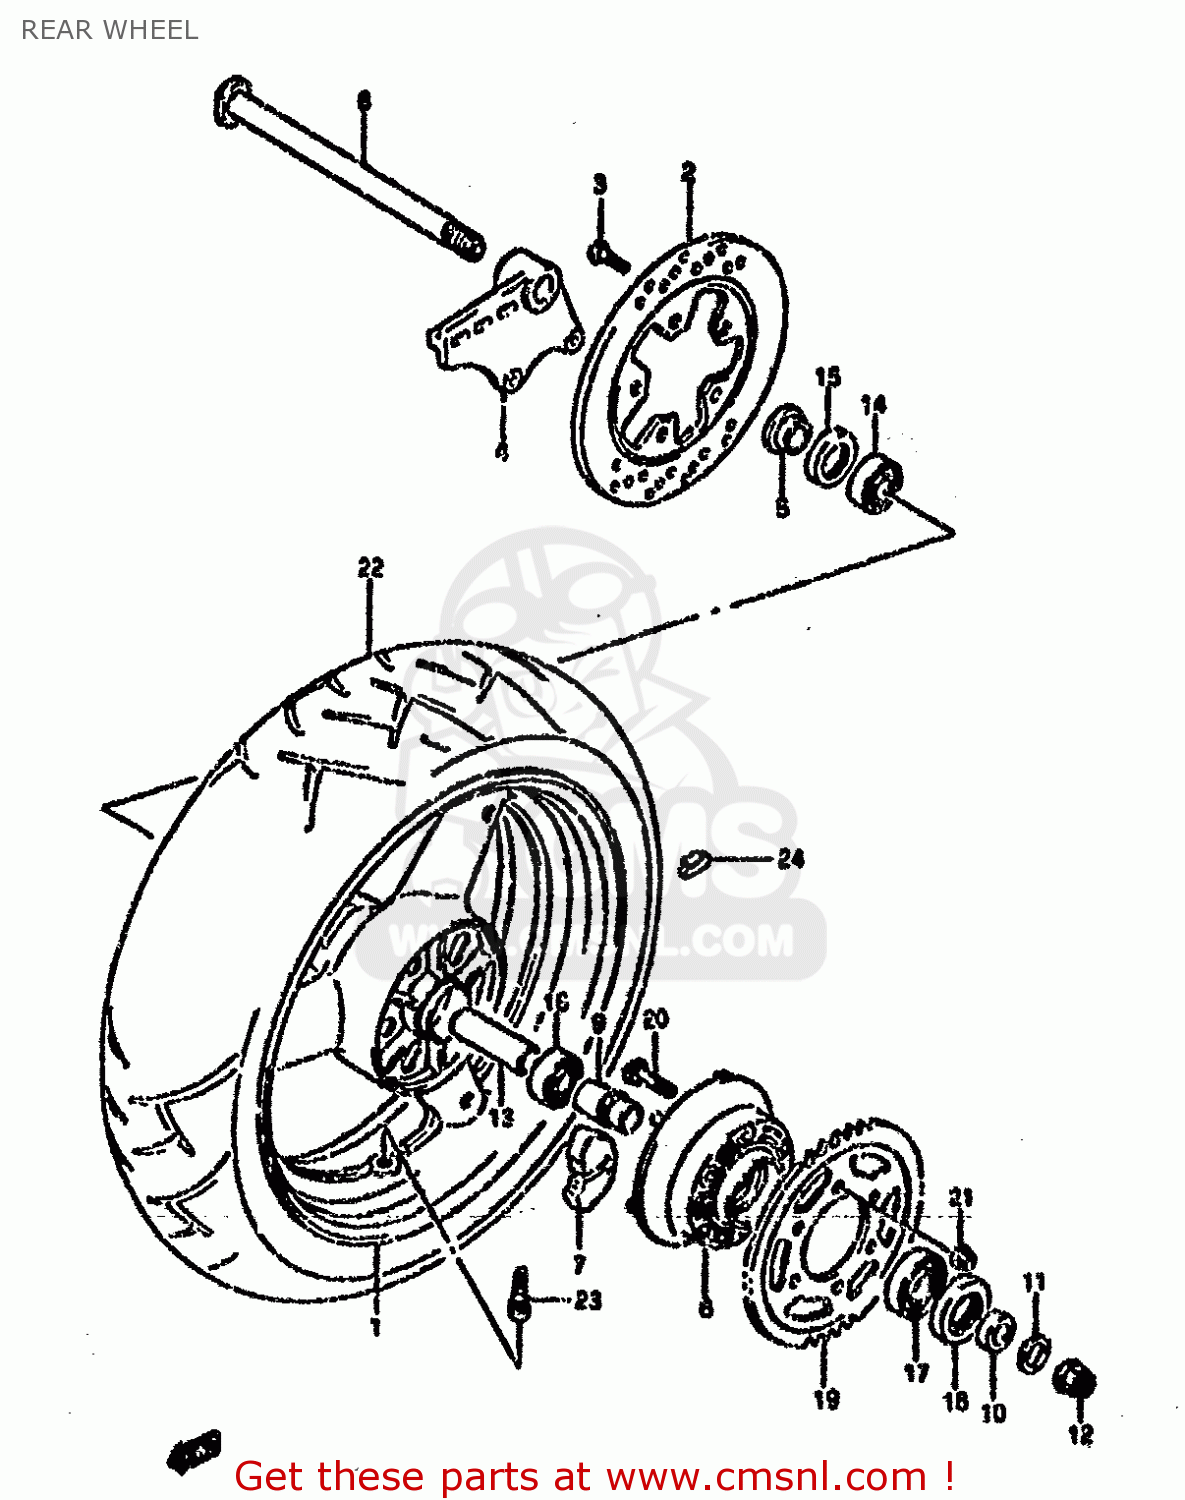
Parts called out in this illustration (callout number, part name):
1	WHEEL,REAR
2	DISC,RR BRAKE
3	BOLT 8X33
4	BRACKET,RR CALIPER
5	SPACER,RR AXLE,R
6	DRUM,RR SPROCKET
7	ABSORBER,RR HUB SHOCK
8	AXLE,REAR
9	RETAINER,RR HUB BEARING
10	SPACER,RR AXLE,L
11	WASHER (18.2X28X2.6)
12	NUT
13	SPACER,RR WHEEL HUB BEARING
14	BEARING(20X47X14)
15	SEAL,BEARING OIL RH
16	BEARING(20X47X14)
17	BEARING(25X62X17)
18	SEAL,OIL(35X62X8)
19	SPROCKET,REAR (NT:41)
20	BOLT
21	NUT
22	TIRE,REAR 180/55 ZR17
23	VALVE ASSEMBLY,WHEEL,TR412
24	BALANCER,WHEEL
